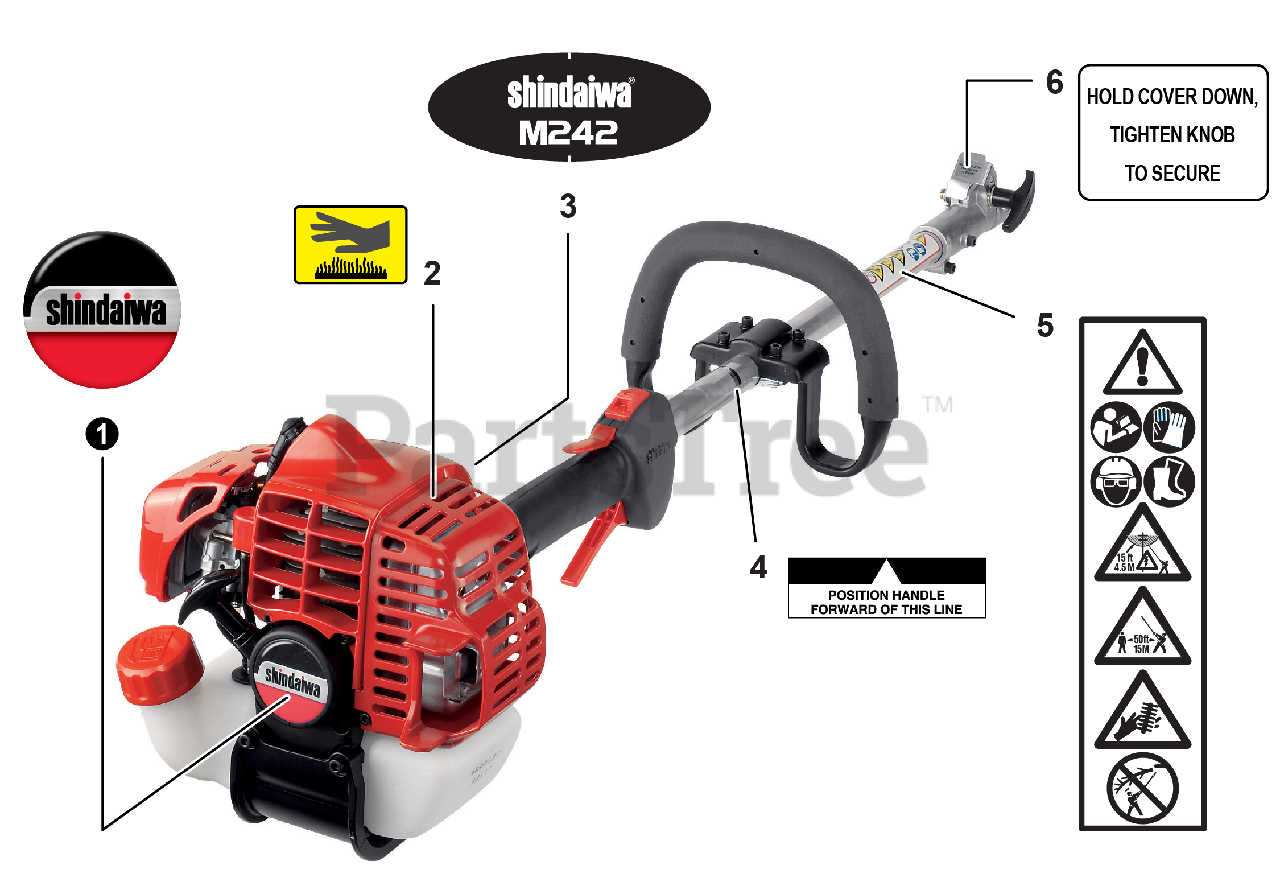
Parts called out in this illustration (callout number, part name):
1	LABEL, SHINDAIWA
2	LABEL, CAUTION - HOT
3	LABEL, MODEL - M242
4	LABEL, HANDLE
5	LABEL, CAUTION
6	LABEL, LATCH INSTRUCTION
